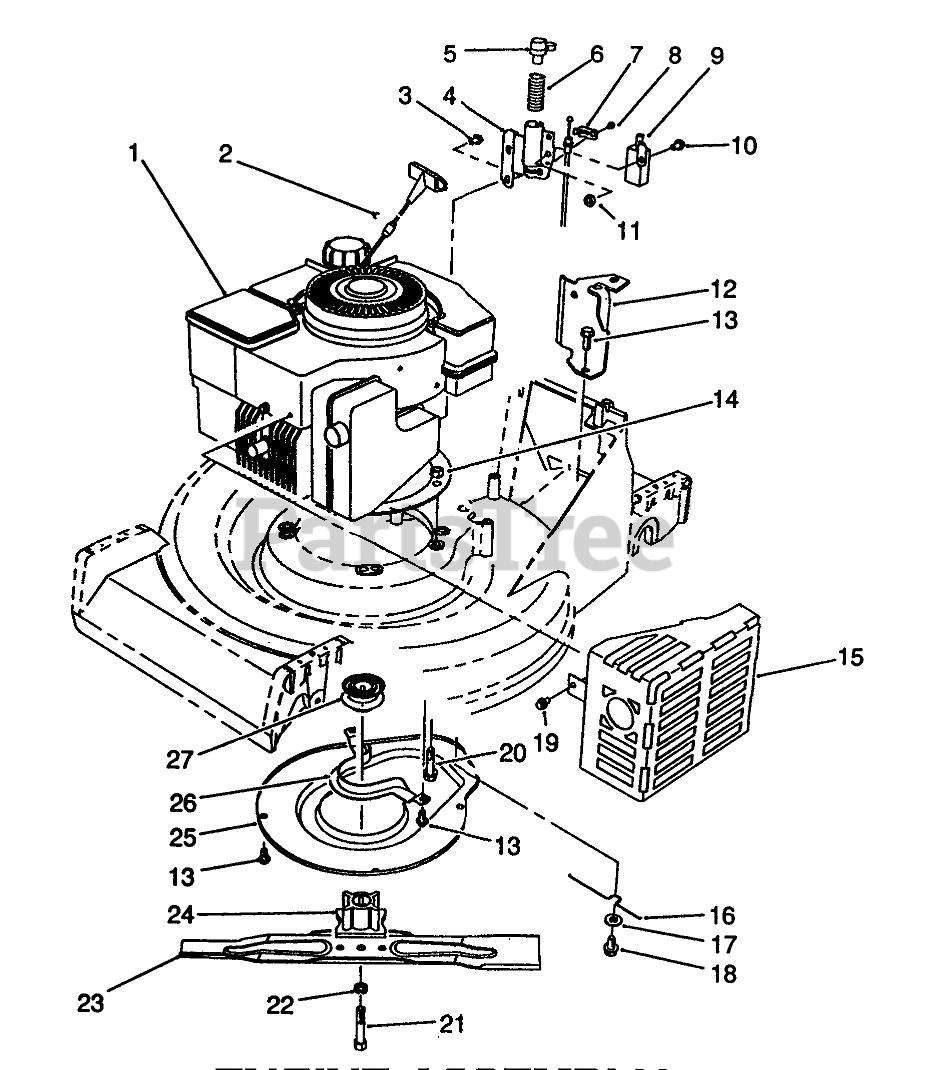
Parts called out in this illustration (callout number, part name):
2	STAPLE
3	SCREW
4	TUBE WA
5	BRAKE PAD/PLUNGER ASM
6	COMP SPRING
7	CABLE CLAMP
8	SCREW
9	PUSH BUTTON SWITCH
10	SCREW-HH
11	NUT-LOCK, NI
12	Bracket-Cable Support
13	SCREW-HWHTF
14	Nut
15	HEAT SHIELD WA
16	RETAINER-BELT
17	WASHER-FLAT
18	SCREW-HHFTF
19	SCREW-HH
20	SCREW-HH
21	SCREW-BLADE
22	WASHER-LOCK
23	Key
24	BLADE RETAINER
25	Cover
26	Guide-Belt
27	PULLEY-DRIVE, ZONE START
